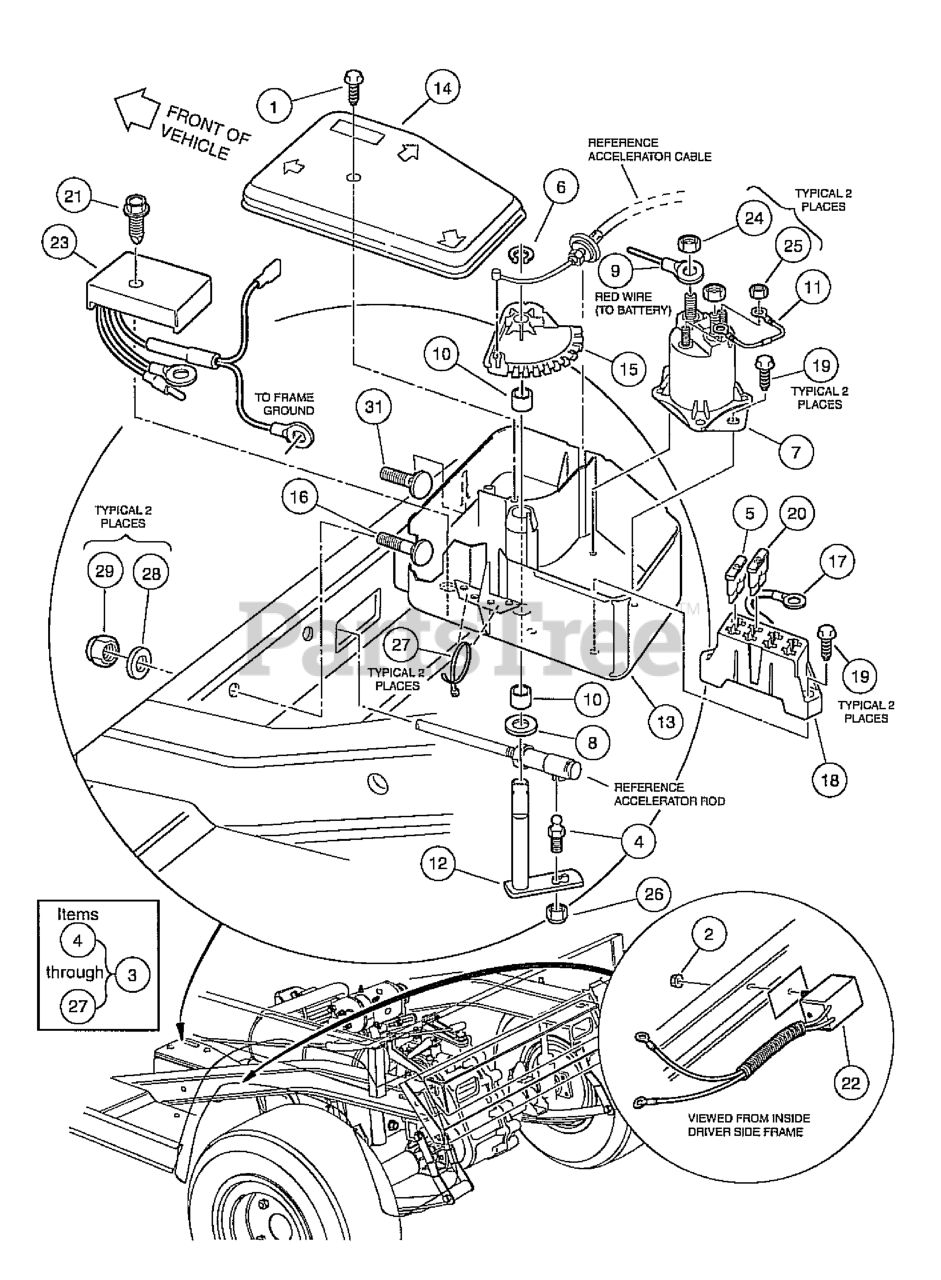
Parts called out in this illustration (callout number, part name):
1	SCREW, #12-16 X .625 HI-LO
2	LOCKNUT, 5/16-18 HEX FLANGE
3	Assembly, Electrical Component Box
5	10 AMP FUSE
7	SOLENOID, 12 VOLT
9	WIRE ASSY #6 RED
10	BUSHING, SECONDARY WGHT SPLIT
11	ASM, DIODE
12	BELL CRANK AND SHAFT ASSY
13	BOX, ELECTRICAL COMPONENT
14	COVER, OHV ELECTRIC BOX
15	CAM, ELECTRIC BOX
16	BOLT,5/16-18 X 2.0 RD HD SQ NK
17	WIRE ASSY, #10 RED
18	FUSE BLOCK
19	SCREW, #12-16 X .625 HI-LO
20	FUSE - 20 AMP
21	SCREW, 1/4-15 X 1.50 HI-LO HEX
22	DIODE ASSY
23	ASM, VOLTAGE REGULATOR
24	NUT, 5/16-18 HEX
25	NUT, #10-32 HEX
26	LOCKNUT, 1/4-28 NYLON INSERT
27	TIE WRAP, 8" NYLON
28	WASHER, 5/16 TYPE A FLAT
29	LOCKNUT, 5/16-18 NYLON INSERT
30	BOLT 5/16-18 X 1.5
